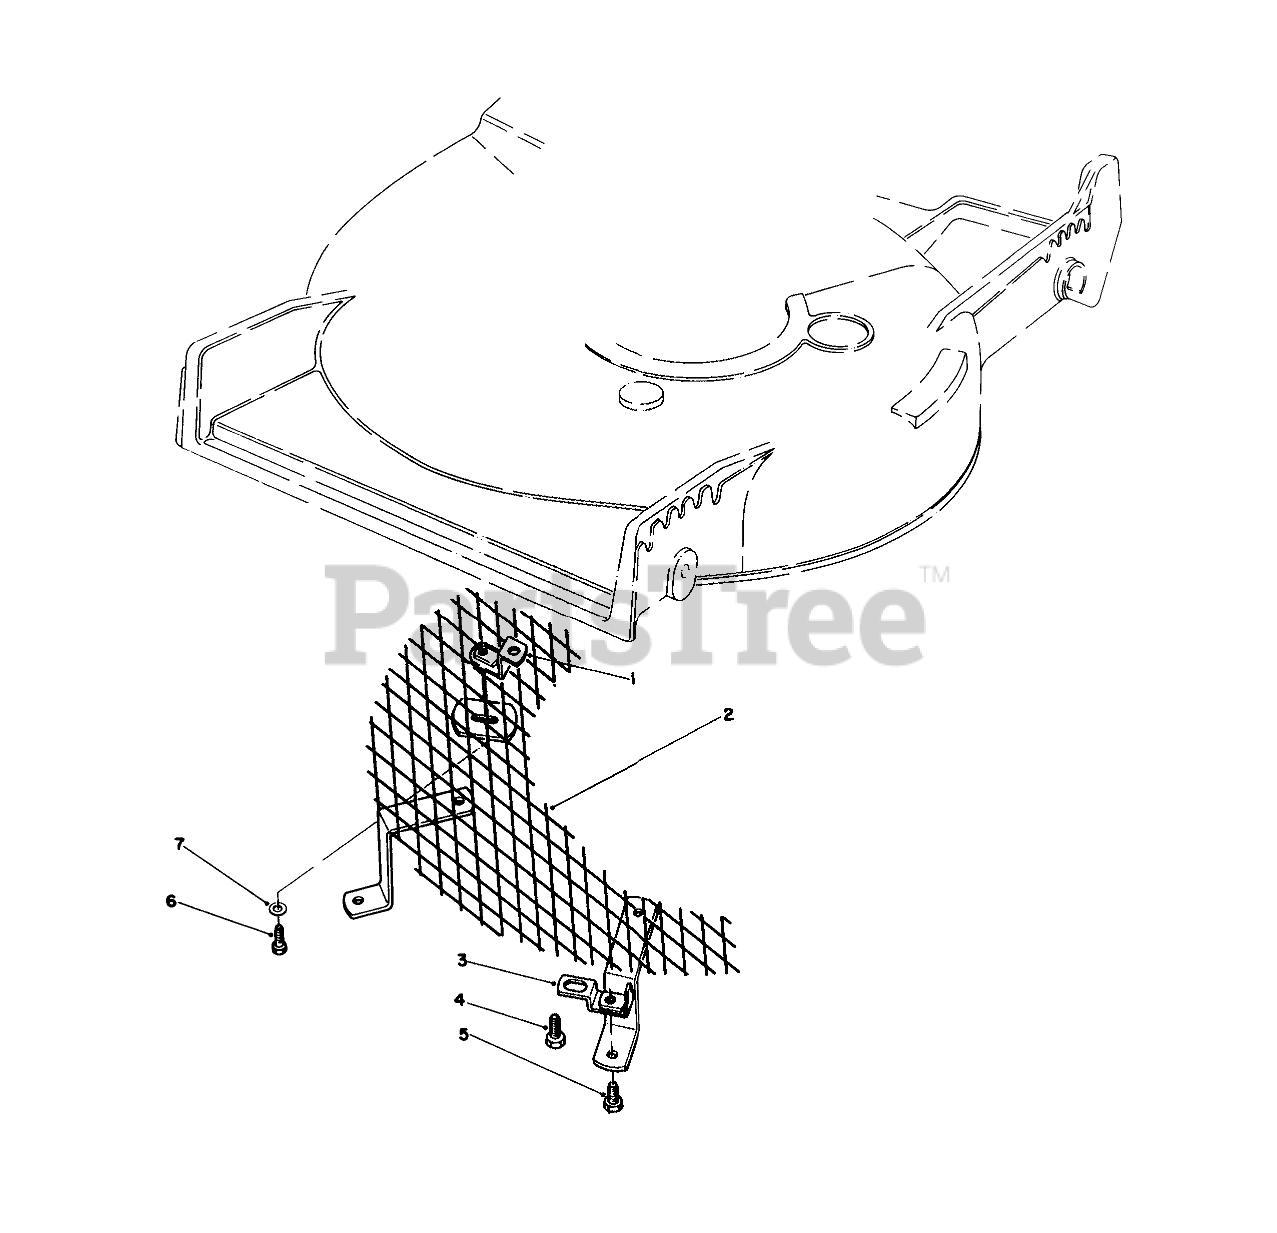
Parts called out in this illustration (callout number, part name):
1	BRACKET WA
2	SCREEN WA
3	MTG. BRACKET W.A.
4	SCREW-HWHTF
5	SCREW-HH
6	SCREW-HH
7	WASHER-FLAT
